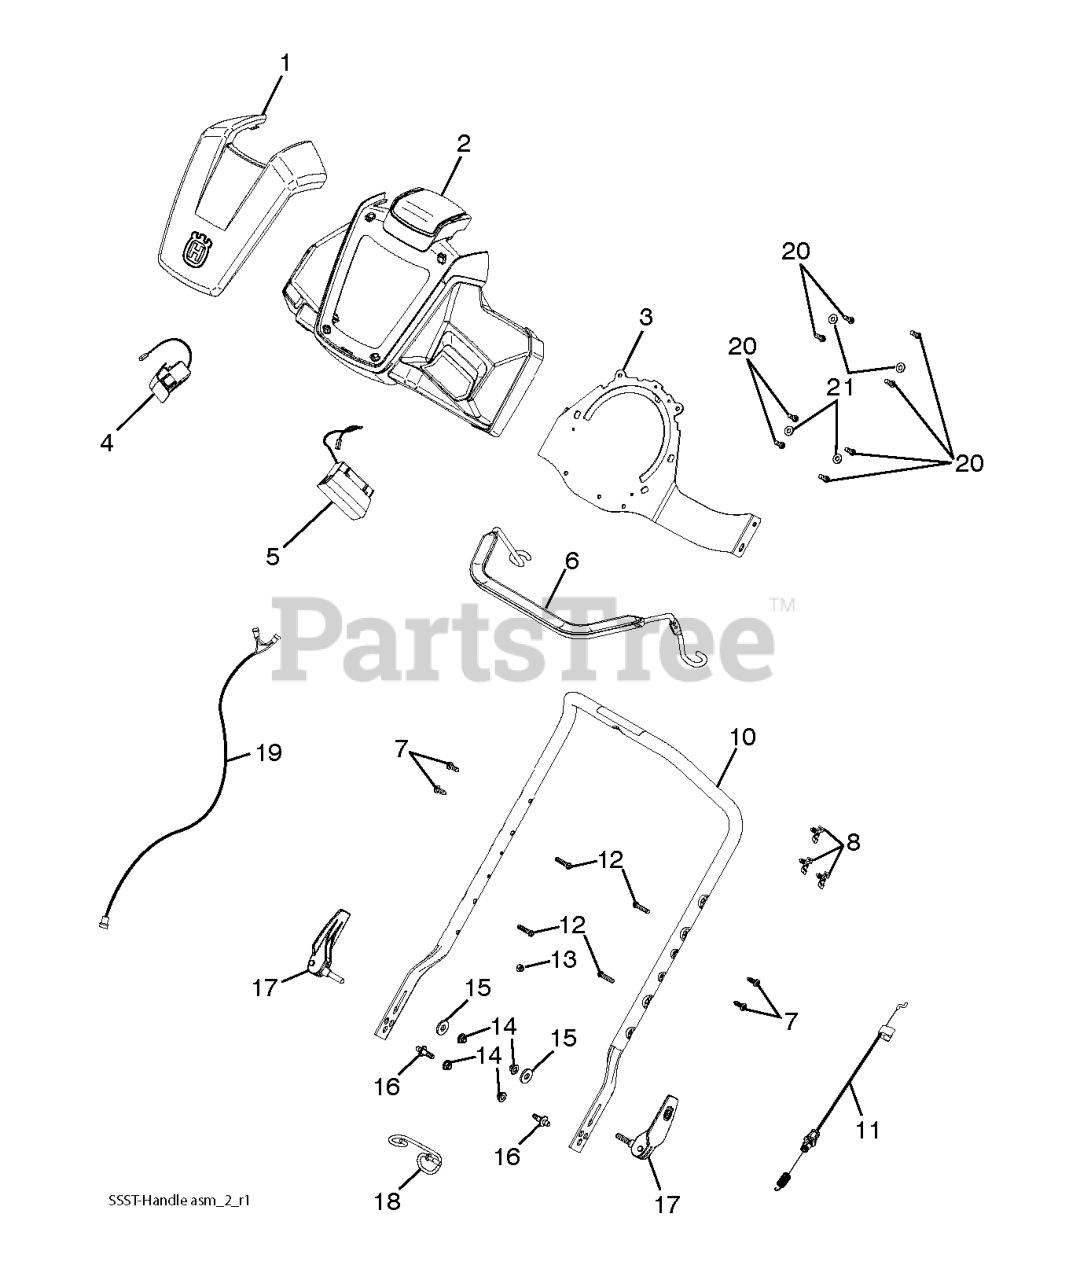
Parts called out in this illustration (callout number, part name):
1	SUBASM.CONTROL.SHROUD
2	COVER.HANDLE.LG.SHROUD
3	BRACKET.SUPPORT.DCC.STAMP
4	RP SUBASM.RH.LED.SGL.STAGE.SNO
5	SUBASM.LH.LED.SINGLE.STAGE.SNO
6	BAIL.OVERMOLD.HUSQ.SSST.BLACK
7	SCREW.PAN.HD.TORX.1/4-20X.750
10	HANDLE.UPPER.ERGO.SSST.GREY
11	CABLE.CLUTCH.SSST.SHORT
12	SCREW.HWH.13-16X1.12
13	NUT
14	NUT 5/16- 18 FLANGE NYLOCK.BLK
15	WASHER,HARDEN
17	SUBASM.QUICK.ADJUST.COLD
18	GUIDE.ROPE.SNOW
19	HARNESS.LED
20	SCREW.HX.13X.750
21	WASHER
